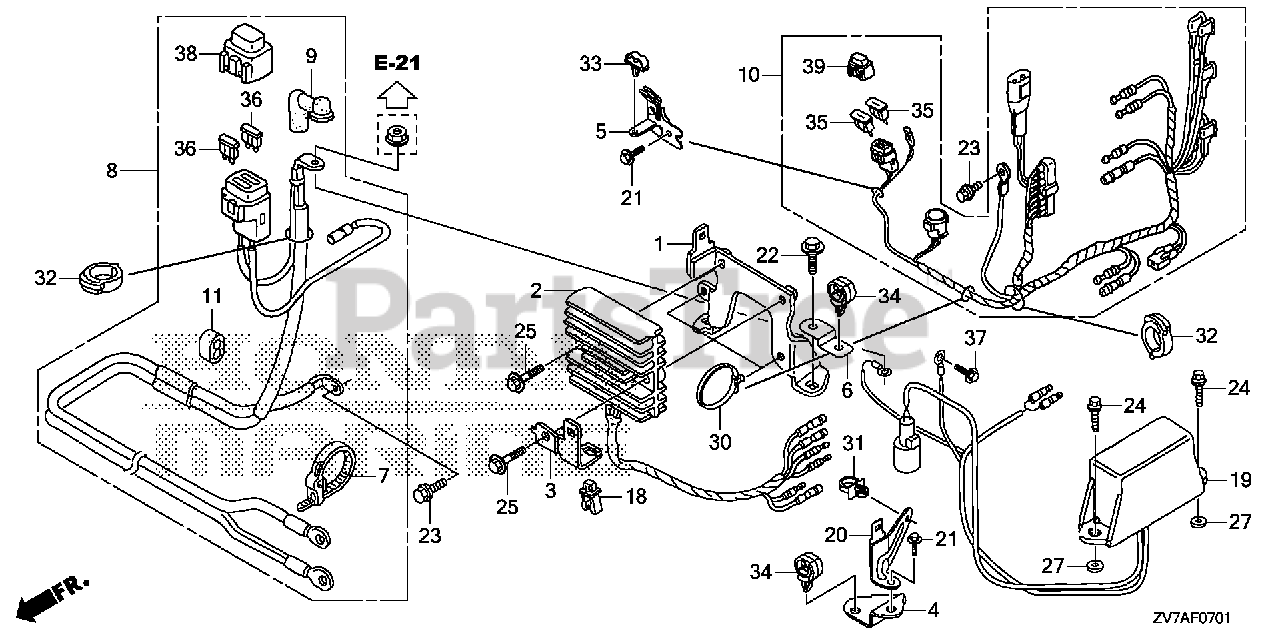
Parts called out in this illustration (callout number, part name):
1	BRACKET, REGULATOR
2	RECTIFIER ASSY., REGULATOR (12A)
3	BRACKET, CONNECTOR
5	BRACKET, FUSE CASE
7	BAND, WIRE
7	BAND, WIRE (165MM) (BLACK)
8	CABLE ASSY., STARTER
9	COVER, TERMINAL
10	CABLE ASSY., REMOTE CONTROL (A)
11	CLAMP, IGNITION WIRE
18	CLIP B, AIR TEMPERATURE SWITCH WIRE
21	BOLT, FLANGE (6X14) (CT200)
22	BOLT, FLANGE (6X12) (CT200)
23	BOLT, FLANGE (6X12) (CT200)
25	BOLT, FLANGE (6X20)
30	STRAP, CABLE (118MM) (BLACK)
32	CLIP, WIRE HARNESS
33	CLIP, CORD
35	FUSE, BLADE (10A)
36	FUSE, BLADE (15A)
38	COVER ASSY., FUSE (15A)
39	COVER ASSY., FUSE (10A)
